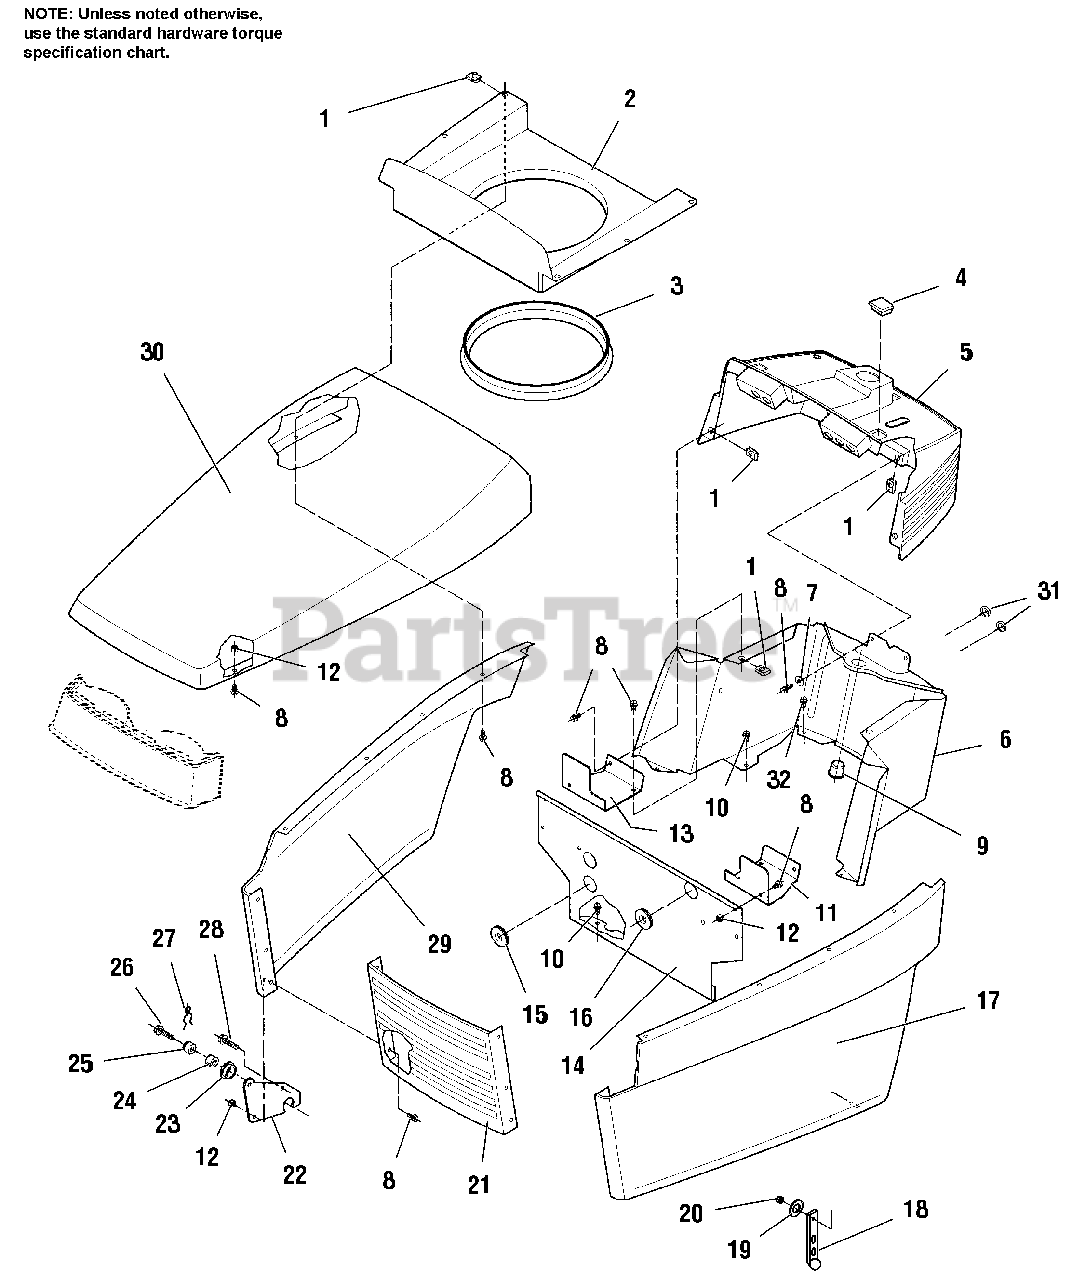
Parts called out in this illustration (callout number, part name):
1	PAL NUT, 1/4-20
3	MOLDING, Air Duct
4	PLUG, Hole, Electric Lift
5	DASH ASSY.
6	DASH, Lower
7	WASHER, Plain, 1/4
8	CAPSCREW, Hex Flange Hd, Whizlock, 1/4-20 x 5/8
9	BUSHING, Nylon
10	CAPSCREW, Taptite, 1/4-20 x 1/2
11	SUPPORT, Bulkhead, LH
12	NUT, Hex Nylon Lock, 1/4-20
13	SUPPORT, Bulkhead, RH
14	BULKHEAD
15	GROMMET, Wire Harness
16	GROMMET, Bulkhead
17	SIDE PANEL ASSY., LH, Orange
17	SIDE PANEL ASSY., LH, Red
18	STRAP, Hood
19	WASHER, Special
20	NUT, Hex Nylon Lock, #10-24
21	GRILLE
22	HINGE, Hood
23	SPACER, Hood
25	PIVOT, Hood
26	CAPSCREW, Taptite, 5/16-18 x 1
27	CLIP, Hairpin
28	CAPSCREW, Taptite, 5/16-18 x 5/8
29	SIDE PANEL ASSY., RH, Orange
29	SIDE PANEL ASSY., RH, Red
30	HOOD, Orange
30	HOOD, Red
32	CAPSCREW, Taptite, 1/4-20 x 3/8
